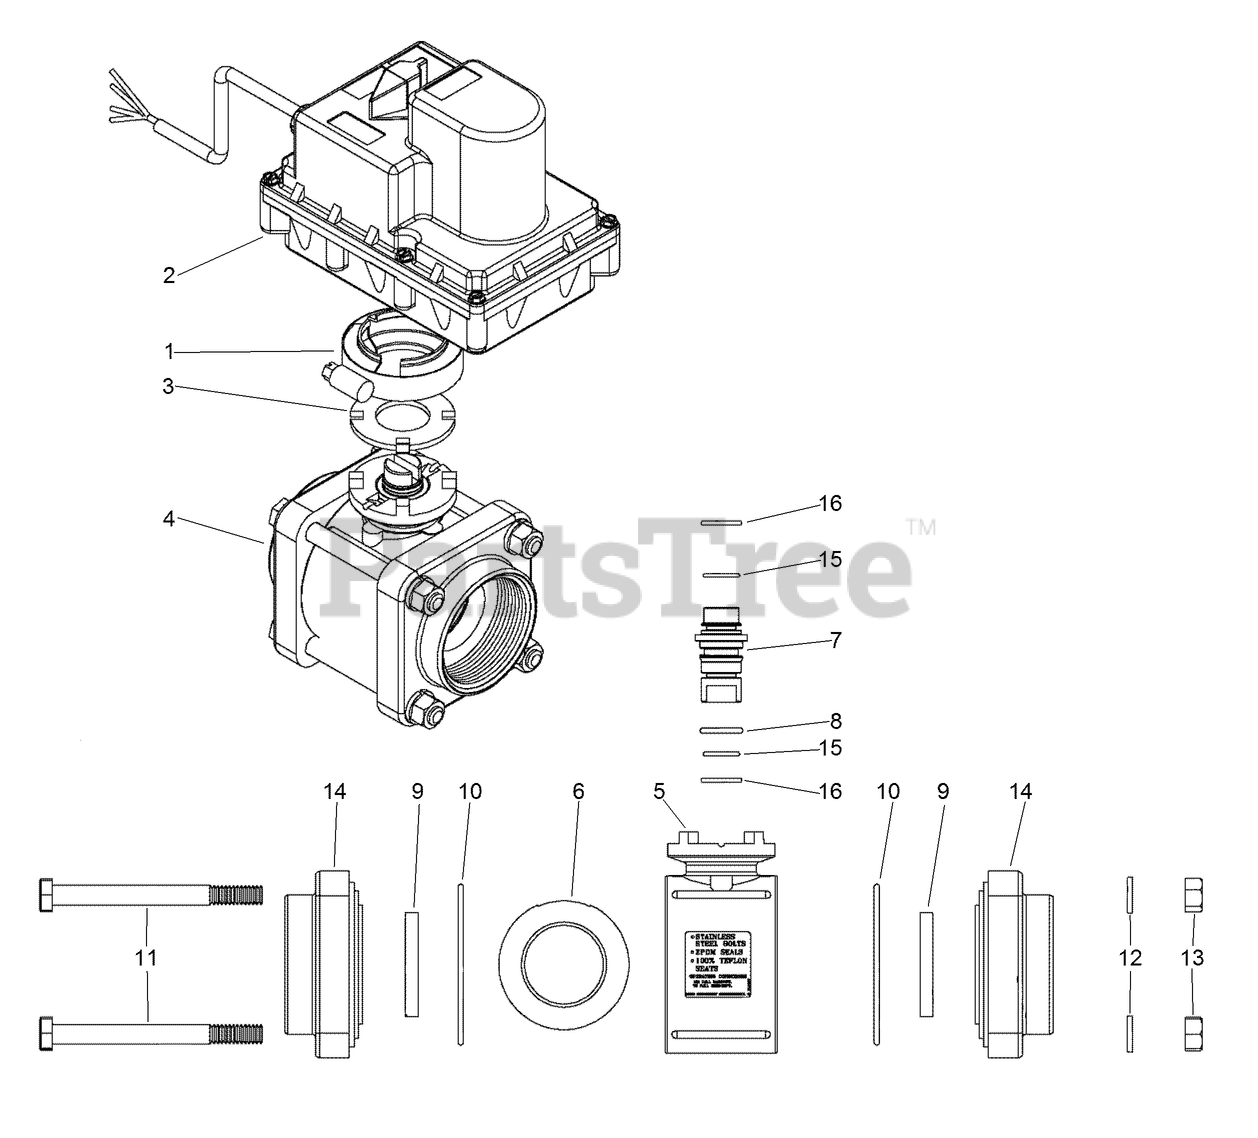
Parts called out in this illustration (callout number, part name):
1	CLAMP-FLANGE
3	FILTER
5	BODY-VALVE
6	BALL-HOLLOW
7	STEM-VALVE
8	O-RING
9	SEAT-VALVE
10	O-RING
11	BOLT - 3/8 x 4
12	WASHER-Spring Lock, Reg 3/8 ZND
13	NUT-Hex 0.375-16 GR5 ZND
14	PLATE-END
15	O-RING
16	SEAL-VALVE
